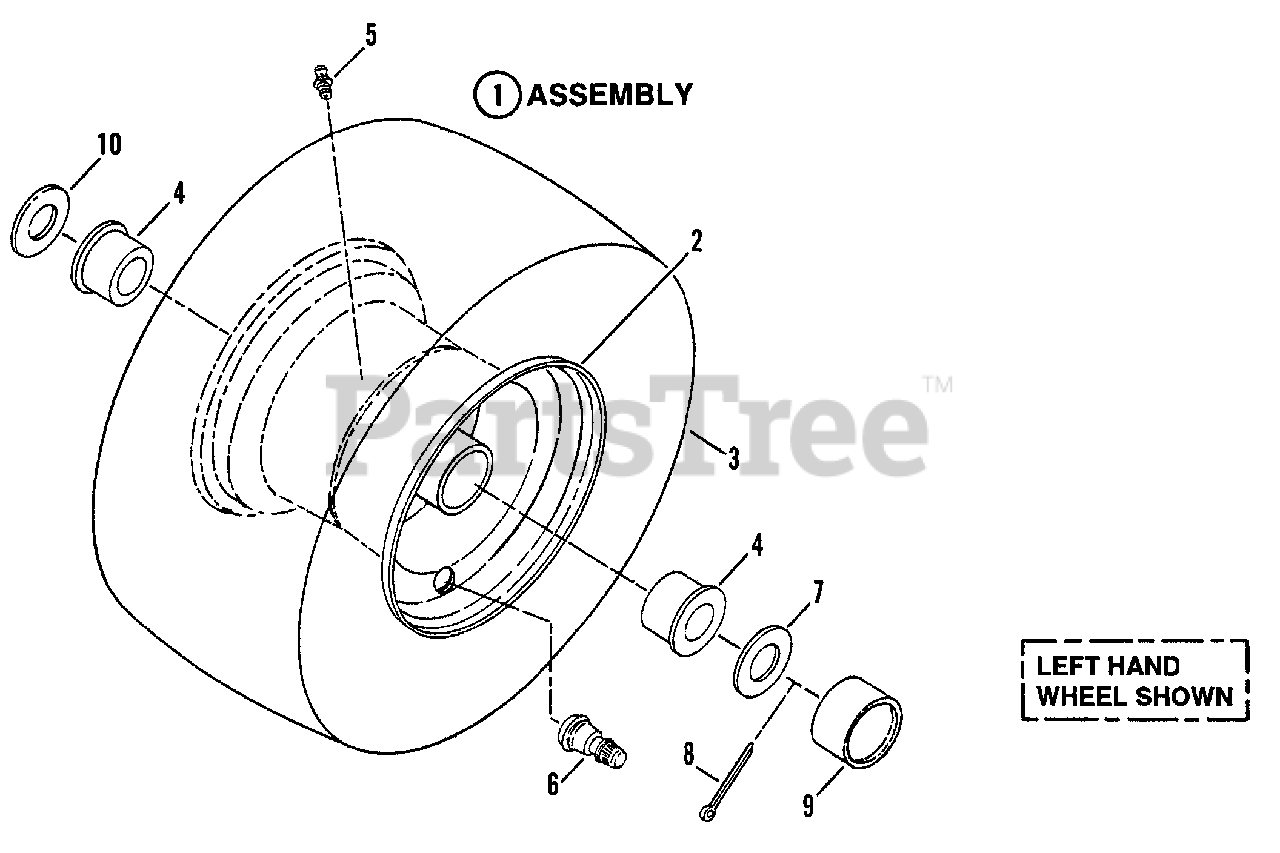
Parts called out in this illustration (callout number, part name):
1	ASSEMBLY, Front Tire & Rim
2	RIM, 6.00 x 4.50
3	TIRE, 15 x 6.00
4	BEARING, Wheel
5	FITTING, Lube 1/4-28 Tapered Thread
6	VALVE, Air (Snap-in)
7	WASHER, 49/64" I.D. x 1 1/2" O.D.
8	COTTER-PIN, 5/32 x1"
9	HUB-CAP
10	WASHER, 25/32" x 1 1/2" O.D.
